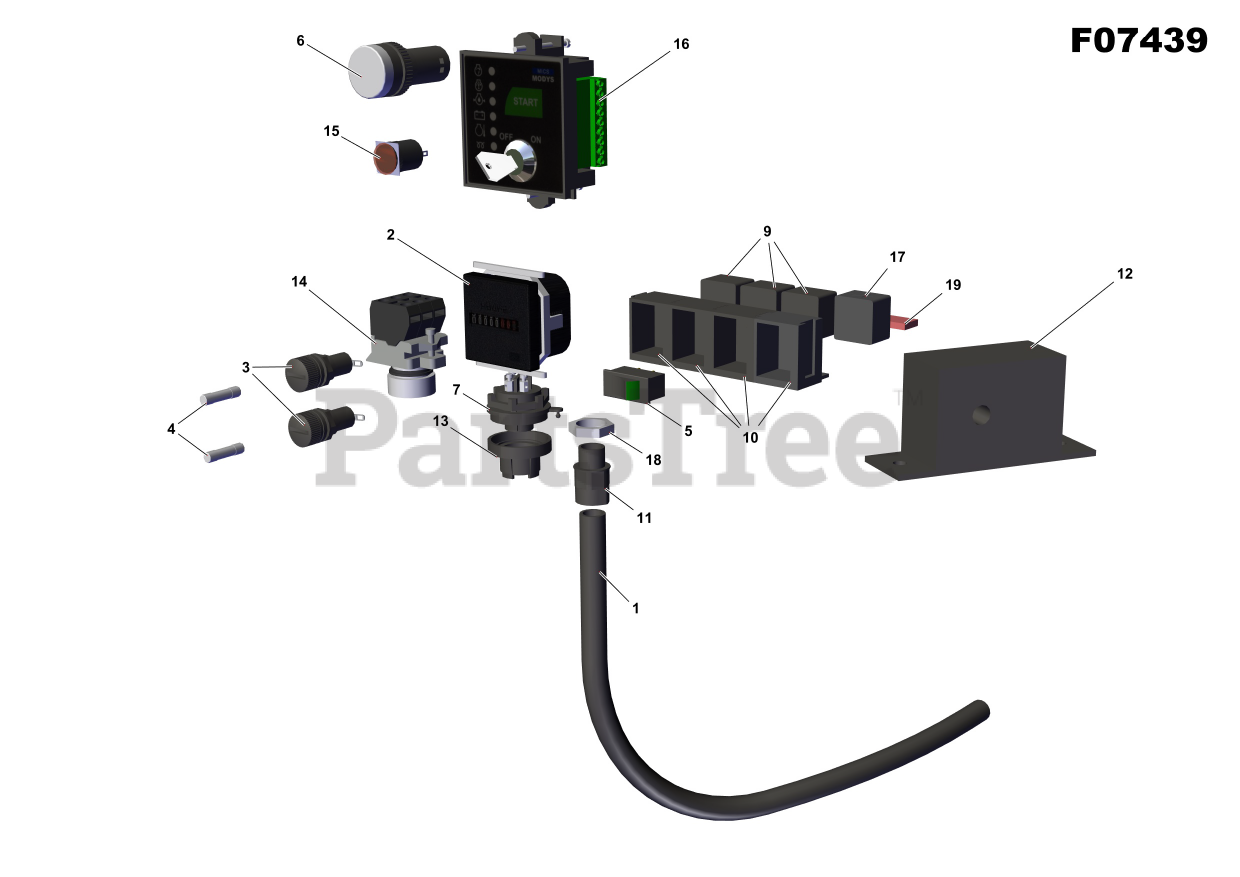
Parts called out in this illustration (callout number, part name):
1	Electrical conduit D12
2	HOUR METER
3	FUSE HOLDER
6	INDICATOR LIGHT W/BLUB
9	Relay 12V 20/30A
10	Relay base
11	Pipe union PG11
12	Automatic idle speed device
14	Pushbutton
15	Indicator light - red led
16	Mics Modys V1.02
16.1	Modys Key
17	Relay 12V
18	Gland nut PG09
19	Fuse ATO 10A red
